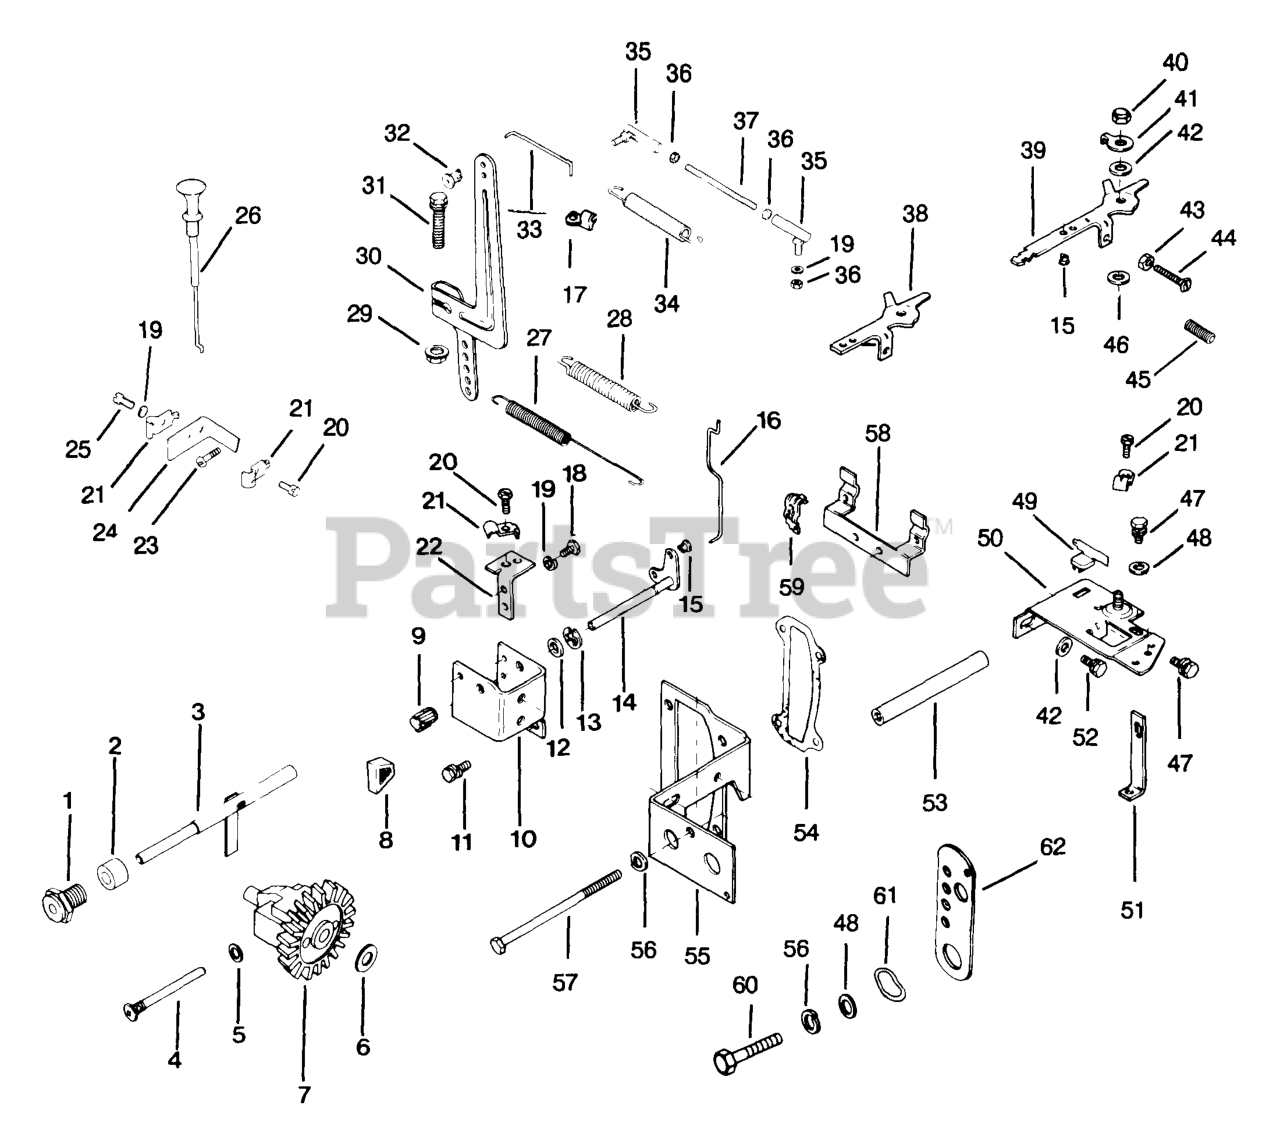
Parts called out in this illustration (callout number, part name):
1	BUSHING
2	SPACER USE 25 112 17-S
3	KIT, SHAFT
7	KIT, GOVERNOR GEAR
8	KNOB - DISCONTINUED
9	KNOB - DISCONTINUED
10	BRACKET - DISCONTINUED
11	SCREW DISCONTINUED
12	BUSHING - DISCONTINUED
14	KIT, LEVER - DISCONTINUED
14	SHAFT, CHOKE CONTROL ASSY - DISCONTINUED
14	SHAFT, CHOKE
15	BUSHING-DISCONTINUED
16	LINKAGE, CHOKE - DISCONTINUED
16	LINKAGE, CHOKE
17	BUSHING - USE 25 158 11
20	SCREW, IND SLT HD 10-24X3/8" USE 25 086 79-S
20	SCREW, WSH HD TAP #10-24X13/32" USE 25 086 109-S
21	CLAMP
22	BRACKET - DISCONTINUED
29	PALNUT, 1/4-20
33	LINKAGE
39	LEVER (KM)
40	NUT, LOCK 1/4-20
42	WASHER, FLAT 1/4" (O.D. 5/8")
43	NUT, MACH SCREW #10-24 GRD 2 USE 25 100 17-S
44	SCREW, SLT PAN HD 10-24X1" USE 25 086 65-S
45	SCREW, SKT SET #10-24X1" - DISCONTINUED
46	WASHER, SPRING 1/4"
47	SCREW
48	WASHER, FLAT 1/4" (O.D. 1/2")
49	TERMINAL - USE 25 452 13
50	BRACKET - DISCONTINUED
51	BRACKET - DISCONTINUED
52	SCREW, SEMS 1/4-20X5/8" USE 25 086 539-S
53	SPACER - DISCONTINUED
54	GASKET, CAMSHAFT COVER
55	BRACKET - DISCONTINUED
56	WASHER, SPRING LOCK 1/4"
57	SCREW - DISCONTINUED
58	BRACKET - DISCONTINUED
59	CLIP
